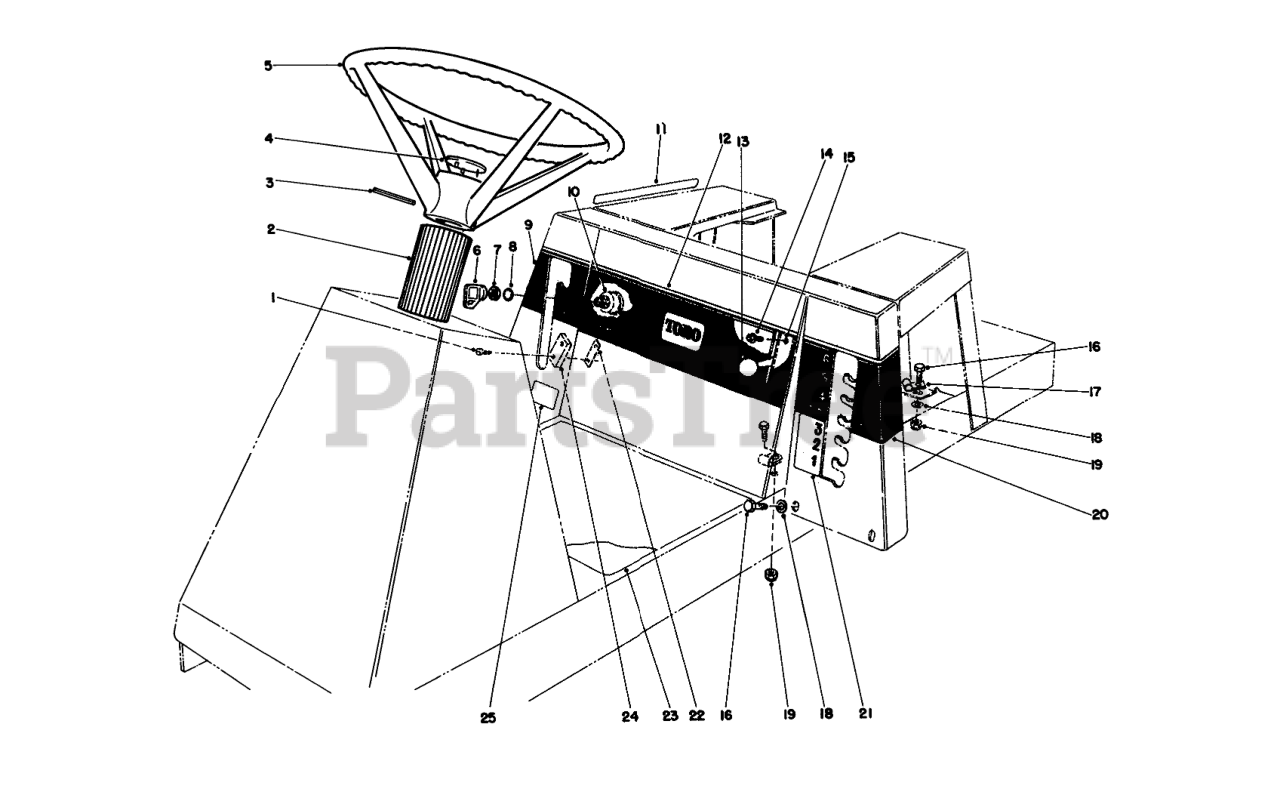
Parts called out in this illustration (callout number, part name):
1	SCREW-SPH
2	COVER-STEERING SHAFT
3	PIN-ROLL
4	STEERING WHEEL INSERT
5	Assy.-Wheel, Steering (Incl. Ref. #4)
6	KEY-IGNITION
7	NUT-HH
8	WASHER-TOOTH, INTERNAL
9	DECAL-UPPER DECK ENGAGE
10	Switch-Ignition (Incl. Ref. #6-8)
11	DECAL - SHIFT PATTERN
12	DECAL-FRT SEAT CONTROLS
13	Knob
14	SCREW-HWHTF
15	Control-Throttle (Incl. Ref. #13)(Model No. 56185)
16	SCREW-HH
17	CLAMP
18	WASHER-PLAIN
19	NUT-LOCK, NI
20	DECAL - UPPER HOC
21	DECAL - LOWER HOC
22	NUT-SPEED
23	INSTRUCTION DECAL
24	SWITCH-MICRO
25	DECAL-LOWER DECK ENGAGE
